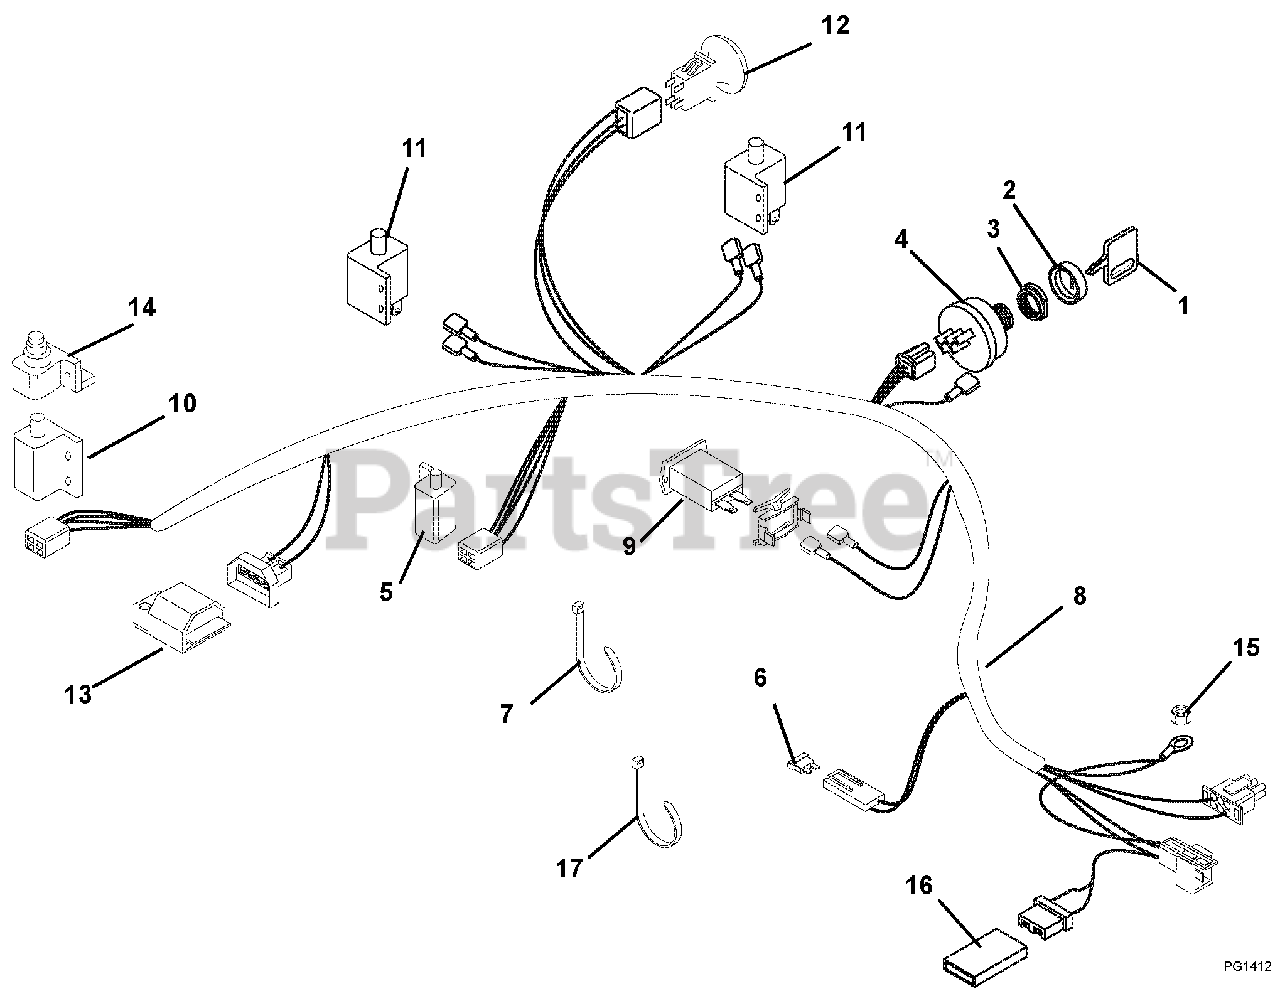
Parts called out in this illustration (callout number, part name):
1	Key- with Cap
2	Cap, Ignition Switch
3	Nut, Panel .562-24
4	Key Switch
5	Switch- Double Pole N.O./N.O.
6	Fuse-25 AMP
7	Tie Wrap-Black
8	Wire Harness
9	Hour Meter-Quartz
10	Switch, Interlock
11	Switch- Single Pole (N.O.)
12	Switch, Clutch With Retainer
13	Module, Interlock, Recoil
14	Boot, Rubber
15	Nut-Locking-Top-Flange .31-18
16	Diode-Connector Shell
17	Tie Wrap
